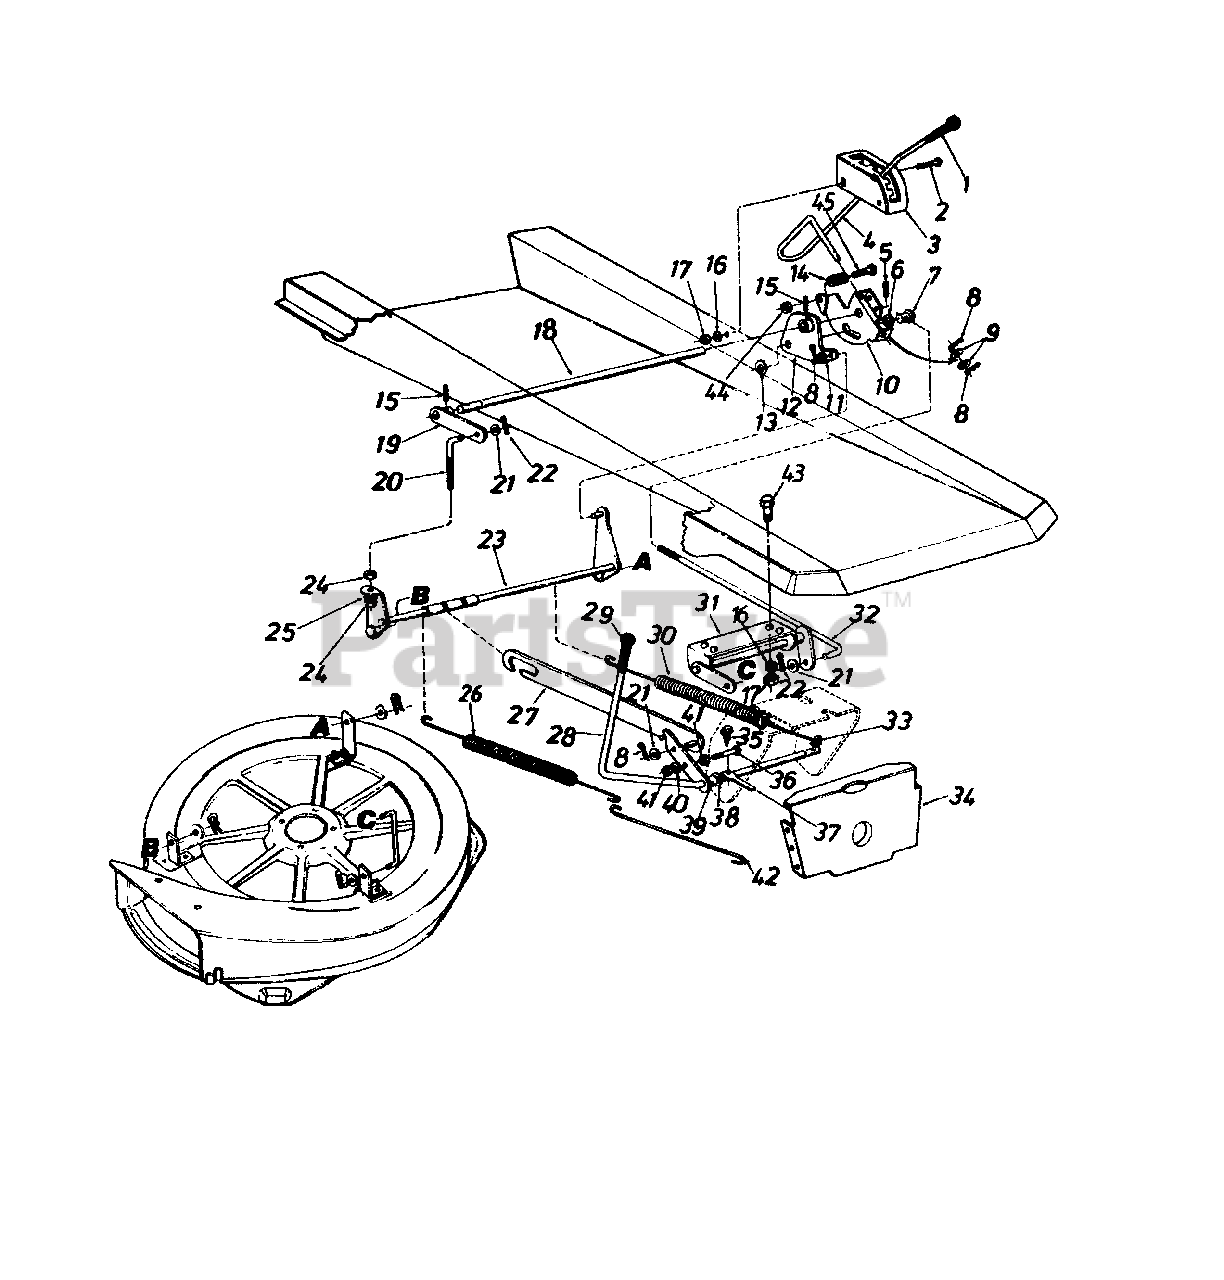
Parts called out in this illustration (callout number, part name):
2	Truss Mach. Scr. 5/16-18 x .75" Lg.
5	Spring Pin Spir. 3/16" Dia. x 1.50" Lg.
6	Fl-Wash. .385" I.D. x .87" O.D.
7	Adj. Ferrule Deck Lift Handle
8	Cotter Pin 1/8" Dia. x 1.0"
9	Fl-Wash. .531" I.D. x .930" O.D.
12	Deck Lift Brkt. Ass'y. - L.H.
13	Fl-Wash. .635" I.D. x 1.04" O.D.
14	Compression Spring .5" Dia. x .9" Lg.
15	Spring Pin Spir. 1/4" Dia. x 1.50" Lg.
16	L-Wash. 5/16" I.D.
17	Hex Nut 5/16-18 Thd.
18	Rear Hgt. Adj. Shaft
19	Deck Lift Brkt. Ass'y. - R.H.
20	Deck Adj. Scr. 3/8-16 Thd.
21	Fl-Wash. .385" I.D. x .87" O.D.
22	Intern. Cotter Pin 1/2" Dia.
23	Deck Link Ass'y. - Rear
24	Hex Nut 3/8-16 Thd.
25	L-Wash. 3/8" I.D.
26	Extension Spring 13.25" Lg.
30	Extension Spring 13.25" Lg.
31	Deck Lift Ass'y. - Front
32	Deck Lift Connecting Rod
33	Clevis Pin Special .250" Dia.
36	Hex Bolt 5/16-18 x 1.50" Lg. (Grade 5)
37	Switch Actuator
38	Fl-Wash. .531" I.D. x .930" O.D.
39	Spacer .511" I.D. x .70" O.D. x .38" Lg.
40	L-Wash. 5/16" I.D.
41	Hex Nut 5/16-18 Thd.
42	Spring Hook
43	Hex Bolt 5/16-18 x .75" Lg.
44	Hex Cent. L-Nut 1/4-20 Thd.
45	Hex Bolt 1/4-20 x 1.25" Lg.
